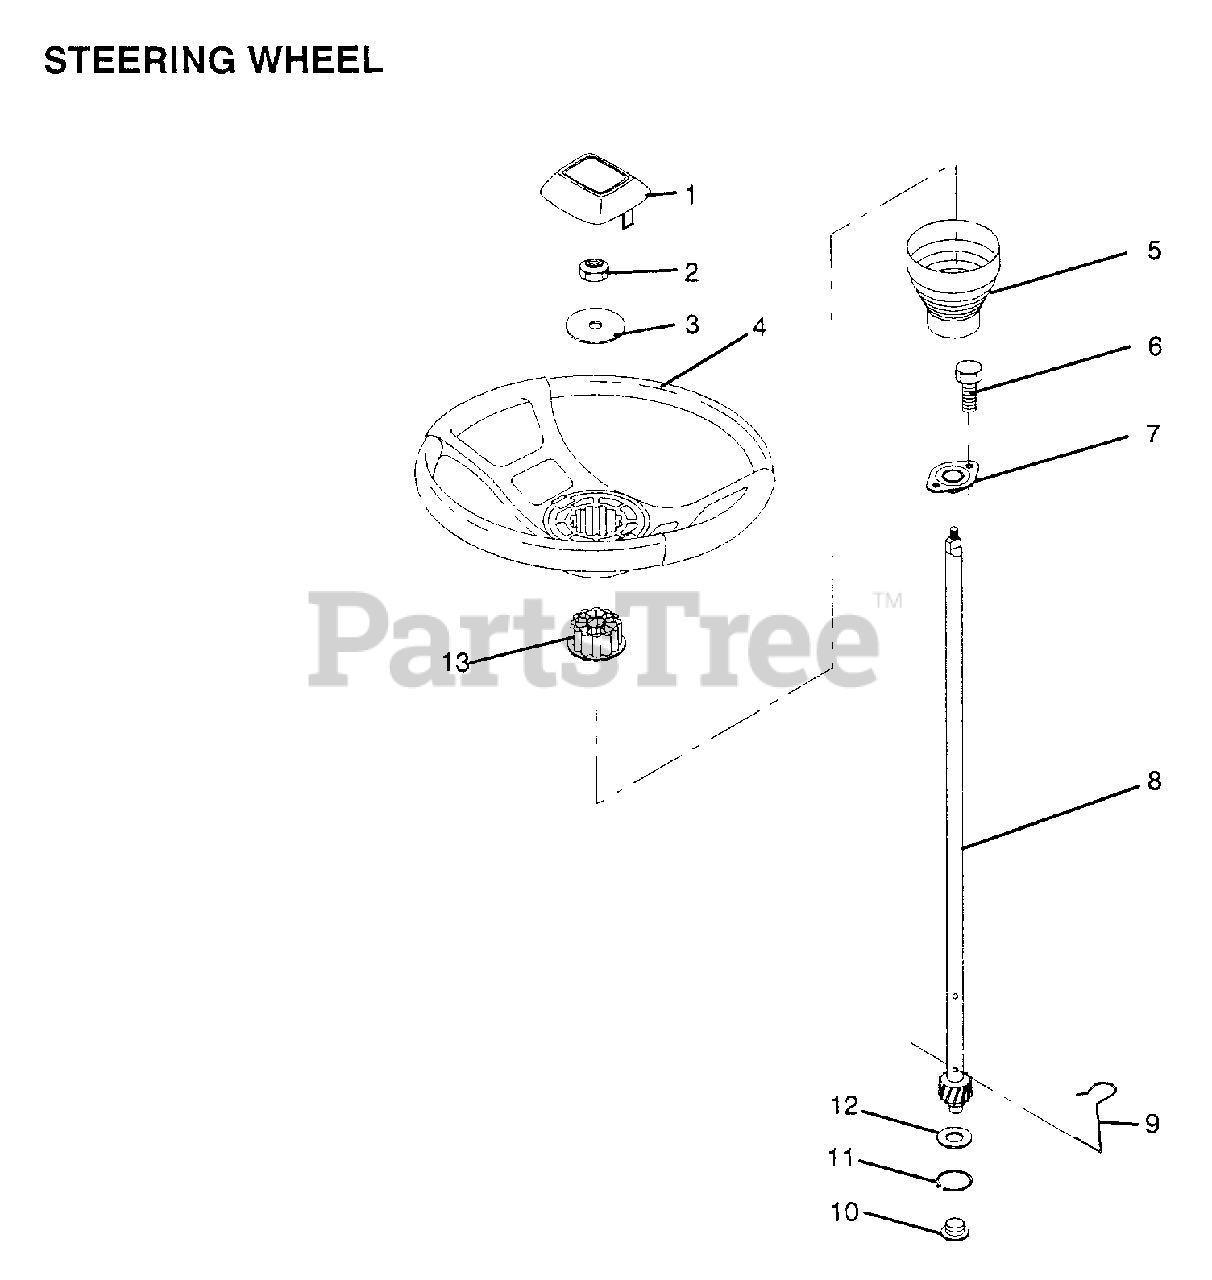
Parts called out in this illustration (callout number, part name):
1	INSERT-WHEEL LT
2	GRIPCO NUT
3	WASHER T
5	SLEEVE STEERING
9	STEERING CLIP
10	BUSHING STEER LWR
11	RING
12	WASHER LT
13	ADAPTER-WHEEL LT
